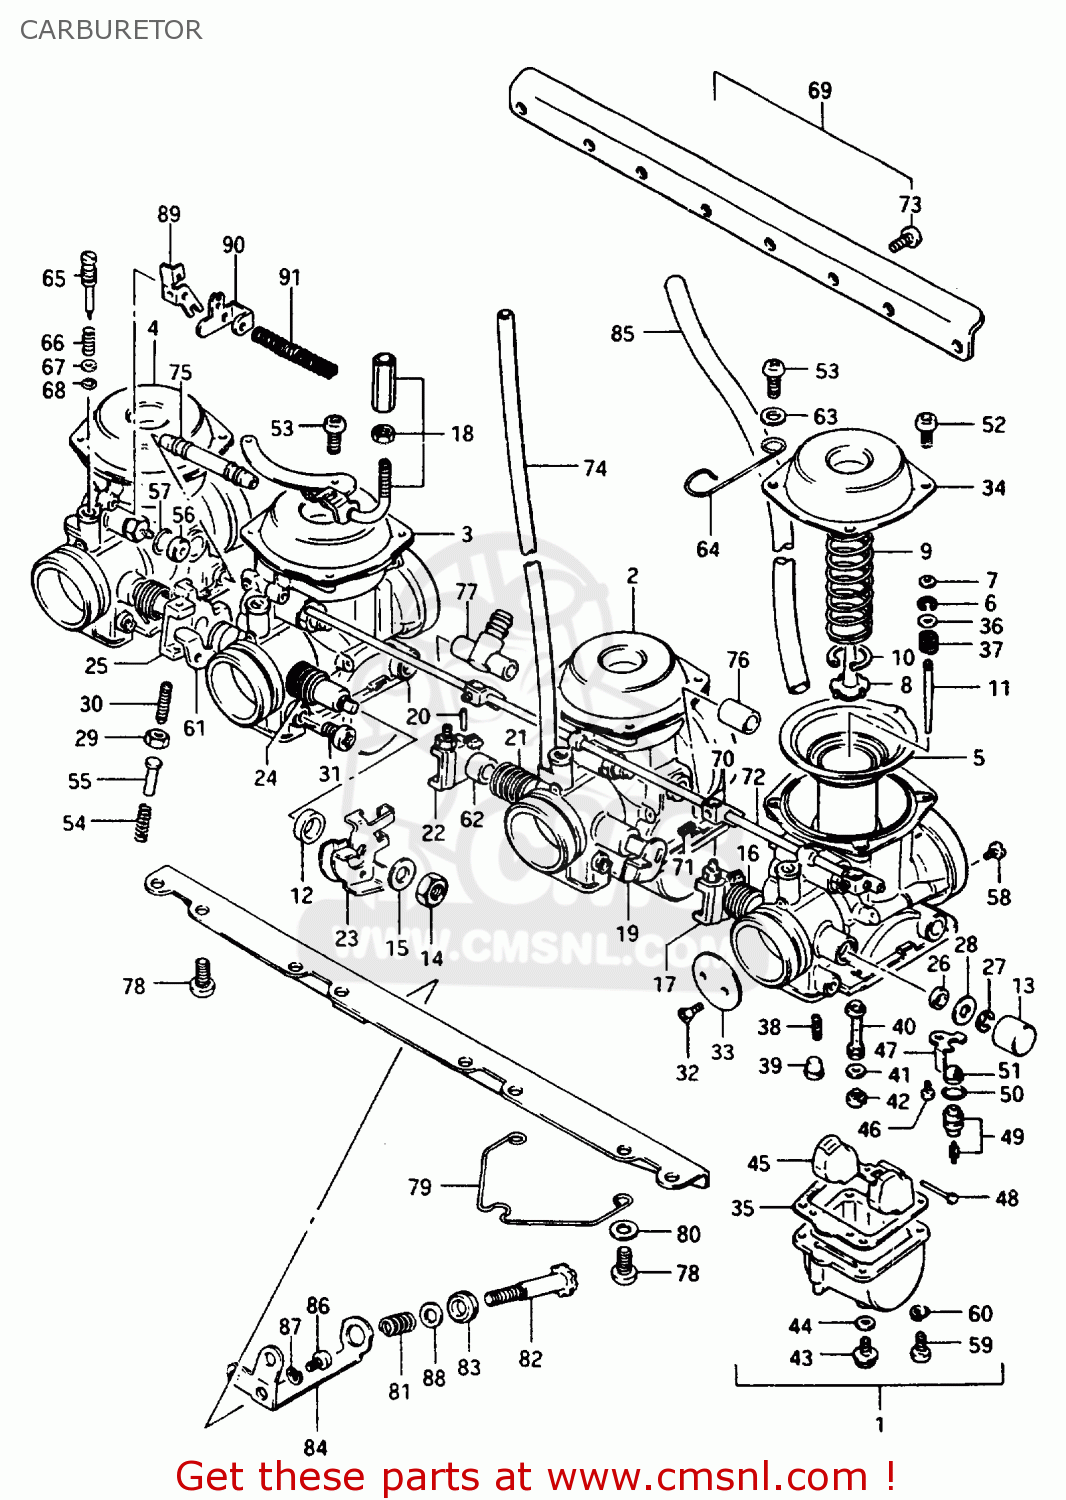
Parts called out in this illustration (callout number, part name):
1	CARBURETOR, LH
2	CARBURETOR, ML
3	CARBURETOR, MR
4	CARBURETOR, RH
5	DIAPHRAGM,CARBURETOR
6	CLIP,NEEDLE
7	RING
8	HOLDER,GUIDE
9	SPRING
10	E RING
11	NEEDLE,JET
12	RING
13	CAP,THROTTLE SHAFT
14	15
15	WASHER
16	SPRING,THROTTLE SHAFT
17	SHAFT,THROTTLE
18	BRACKET
19	SHAFT,THROTTLE
20	PIN,THROTTLE SHAFT
21	SPRING,THROTTLE SHAFT
22	LEVER,THROTTLE SHAFT
23	LEVER
24	SPRING
25	SHAFT,THROTTLE
26	SEAL
27	E RING
28	GASKET,THROTTLE SHAFT (NAS)
29	30
30	SCREW
31	SCREW
32	SCREW
33	VALVE
34	COVER,DIAPHRAGM
35	GASKET,FLOAT CHAMBER (NAS)
36	WASHER
37	SPRING
38	JET, PILOT (47.5)
39	PLUG,NEEDLE JET
40	JET, NEEDLE (X-5)
41	WASHER,NEEDLE NOZZLE
42	JET,MAIN(120)
43	PLUG,DRAIN
44	GASKET (NAS)
45	FLOAT
46	SCREW
47	PLATE,NEEDLE VALVE FITING
48	49
49	VALVE ASSEMBLY,NEEDLE
50	O-RING,NEEDLE VALVE
51	FILTER
52	SCREW
53	SCREW
54	SPRING,THROTTLE SCREW
55	PIN,THROTTLE LEVER
56	57
57	O RING
58	JET,AIR(125)
59	SCREW
60	WASHER,LOCK
61	SHAFT,THROTTLE
62	SPACER,THROTTLE SHAFT
63	WASHER
64	CLIP
65	SCREW,PILOT
66	67
67	68
68	O-RING
69	CARBURETOR ASSEMBLY
70	LEVER
71	SCREW
72	SHAFT,STARTER
73	SCREW
74	HOSE
75	NIPPLE
76	77
77	NIPPLE
78	SCREW
79	CLIP
80	WASHER
81	SPRING
82	ADJUSTER
83	BUSH
84	BRACKET
85	HOSE
86	SCREW
87	WASHER,LOCK
88	WASHER
89	LEVER
90	LEVER
91	SPRING
